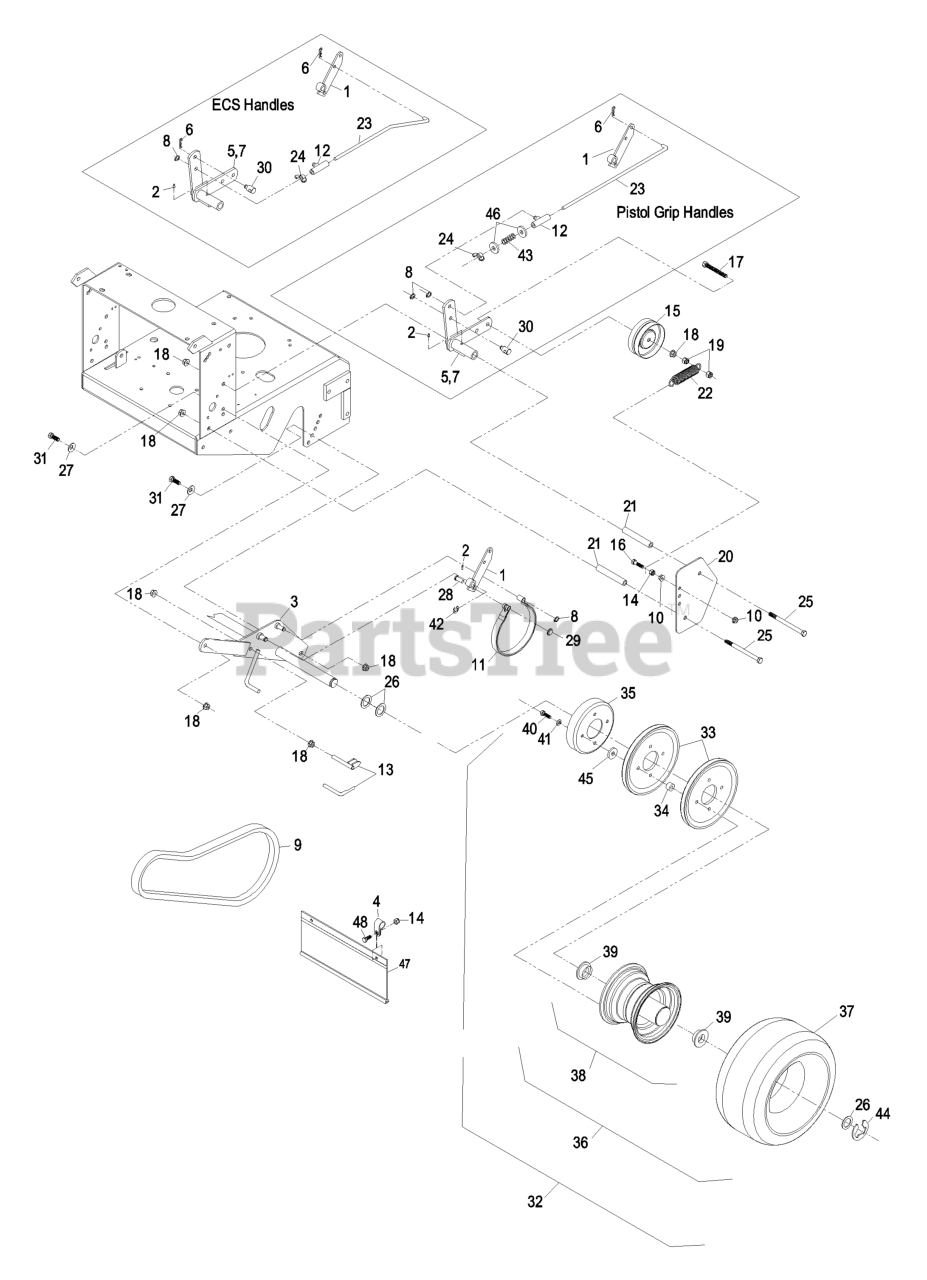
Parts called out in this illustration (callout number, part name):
1	ARM-BRAKE
2	FITTING-GREASE
3	AXLE
4	CLAMP-R
6	PIN-COTTER
8	RING-RETAINING
9	BELT,WHEEL DRIVE
11	BAND-BRAKE
13	SCRAPER
14	NUT-LOCK, NI
15	IDLER-WHEEL, DRIVE
16	SCREW-HH
17	SCREW-HH
18	NUT-HHF, WHIZ
19	NUT-LOCK, NI
20	SHIELD-WHEEL, DRIVE
21	SPACER-SHIELD
22	SPRING-EXTENSION
23	LINKAGE-BRAKE
24	WINGNUT-NYLOCK
25	SCREW-HH
26	WASHER-SPACER
27	WASHER-BELLEVILLE
28	PIN-CLEVIS
29	RING-RETAIN,PUSH,EXT,FLAT
30	SWIVEL-LEVER, DRIVE
31	SCREW-HH
33	SHEAVE-WHEEL, DRIVE
34	SPACER-SHEAVE, WHEEL
35	DRUM-BRAKE
36	WHEEL AND TIRE ASM
37	TIRE-TURFMASTER
38	WHEEL AND HUB ASM
39	BEARING-FLANGED
40	SCREW-HH
41	WASHER-LOCK
42	RING-RETAINING, EXTERNAL
43	SPRING-COMPRESSION
44	RING-SNAP
45	WASHER
46	WASHER-PLAIN
47	SHIELD-TRAILING
48	SCREW-HH
